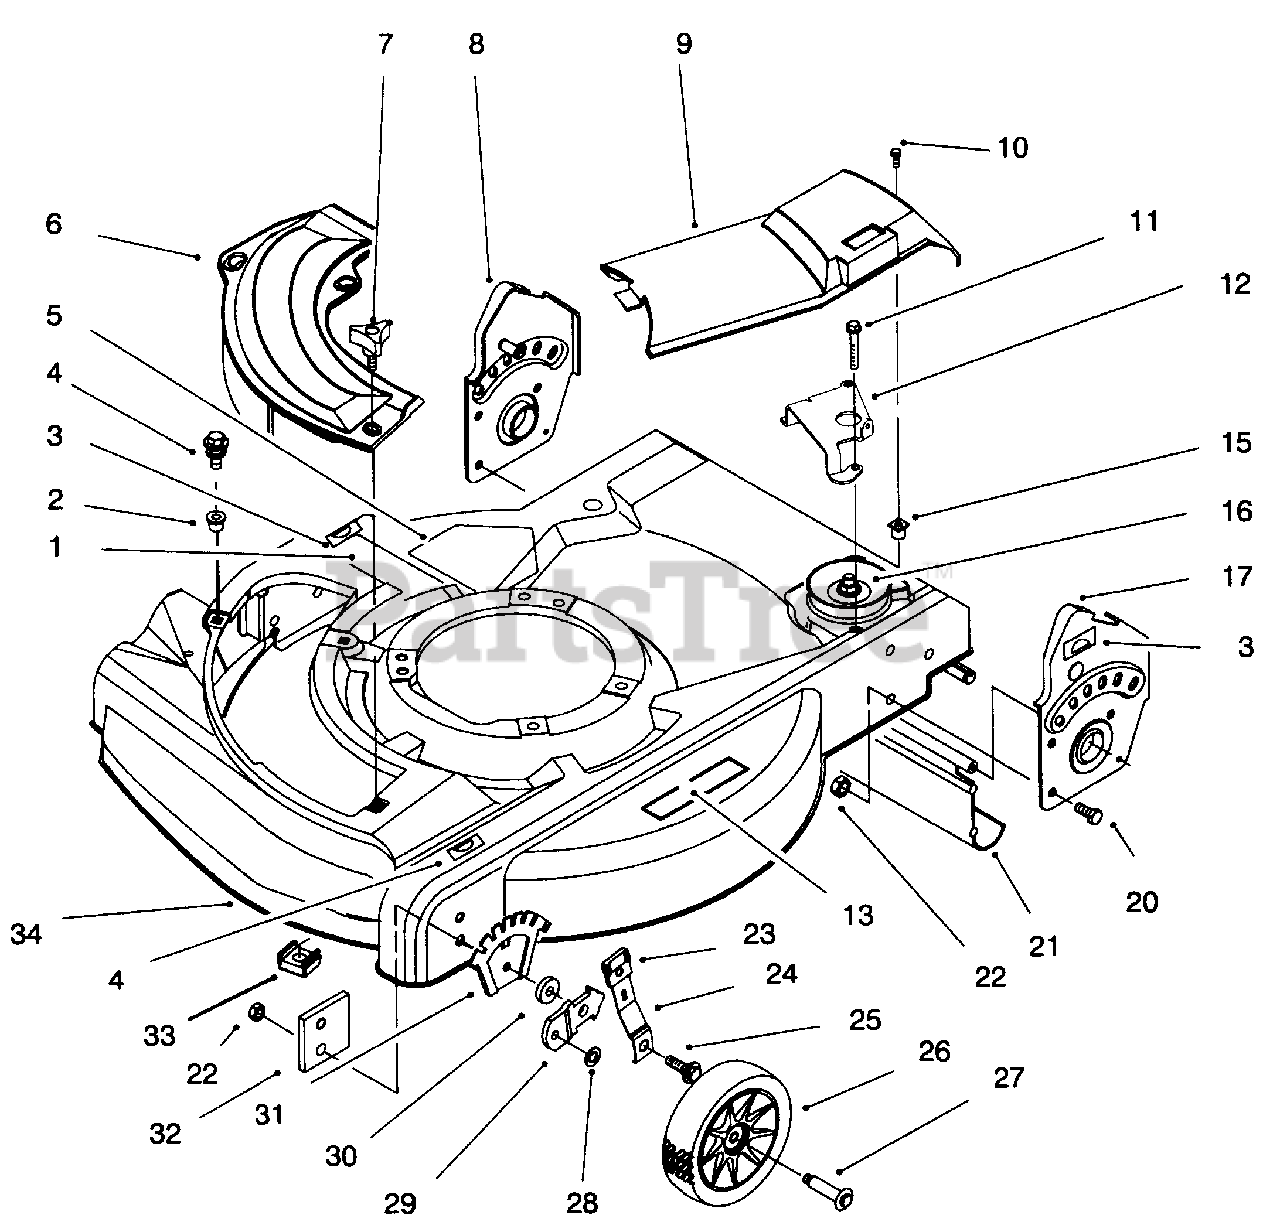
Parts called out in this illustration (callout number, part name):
1	Decal-Danger
2	Grommet-Plastic
3	Decal-H. O. C. L.H.
4	Screw-Thread Forming
5	Decal-Danger
6	Plate-Cover, Mulch
7	Knob
8	Handle Bracket Ass'y-RH
9	Cover-Drive
11	Screw-Thread Forming
12	Guide-Transmission
13	Decal-Warning
15	Grommet-Shroud Mtg.
16	Gear Case Ass'y
17	Handle Bracket Ass'y-L.H.
20	Screw-Hex. Hd.
21	Shield-Trailing
23	Knob-H. O. C.
24	Arm-Spring
25	Bolt-Shoulder
26	Wheel Assembly-6"
27	Bolt-Wheel
29	Bracket-H. O. C.
31	Plate H. O. C.
32	Plate-Baffle
33	Nut-Cage
34	Housing & Baffle Ass'y (Incl. Ref. # 1-5, & 13)
